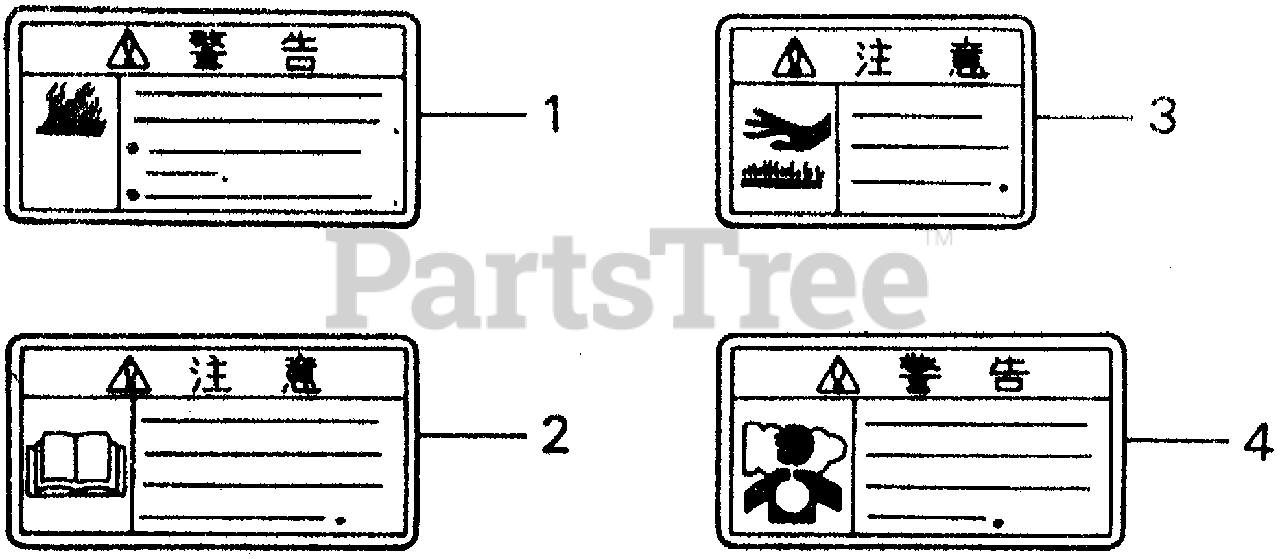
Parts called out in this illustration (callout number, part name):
1	MARK, FUEL WARNING
2	MARK, CAUTION (J)
3	MARK, HEAT CAUTION
4	MARK, EX. GAS WARNING
